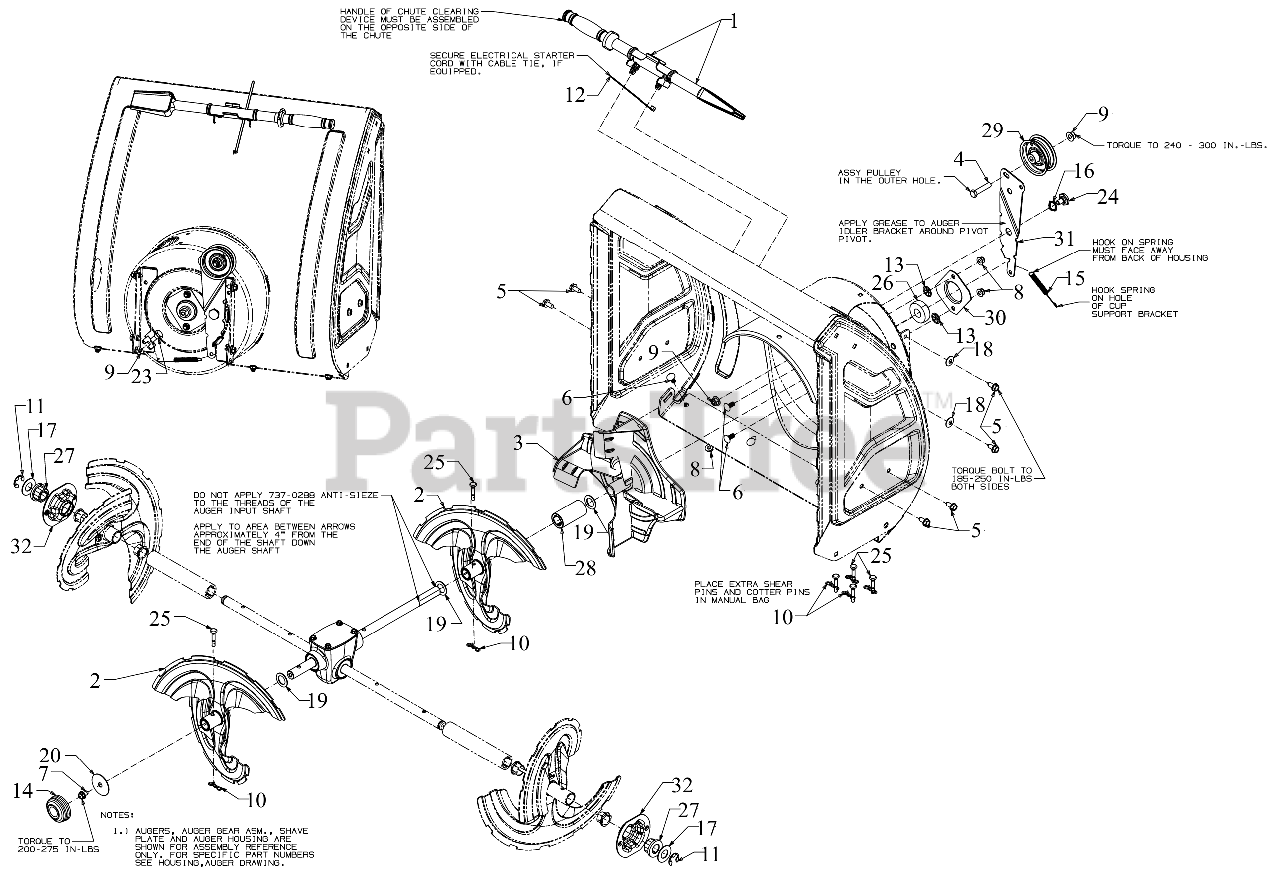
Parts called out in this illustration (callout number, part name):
1	CLEANOUT TOOL
1	CLEANOUT TOOL MOUNTING CLIP
4	HEX SCREW 3/8-16 x 1.75 GR5
5	SCREW 5/16-18 x .750
6	CARRIAGE BOLT 5/16-18 x .75
7	SCREW 5/16-18 x .500
8	FLANGE LOCK NUT 5/16-18
10	BOW TIE COTTER PIN 1/4-5/16
11	E-RING
12	7" CABLE TIE
13	PUSH NUT
15	EXTENSION SPRING .38 OD x 4.59
16	WAVE WASHER .660 ID X.88 OD x .010
17	FLAT WASHER .760ID X1.49OD x .06
18	BELL WASHER .337 X.867 x .057
19	FLAT WASHER .793 ID X1.240X.06
20	HUB CAP WASHER .406 x 1.92 x .060
23	SHOULDER SCREW .498 DIA x .340
24	SHOULDER SCREW .625 DIA x .163
25	SHEAR PIN (.25 x 1.50)
25	Cub Cadet SHEAR PINS (3X SNOW)
26	BEARING W/OUT COLLAR
27	FLANGE BEARING
29	FLAT IDLER PULLEY 2.75 OD
30	BEARING HOUSIN 1.85 ID
31	AUGER IDLER BRACKET
32	HEX BREARING HOUSING
